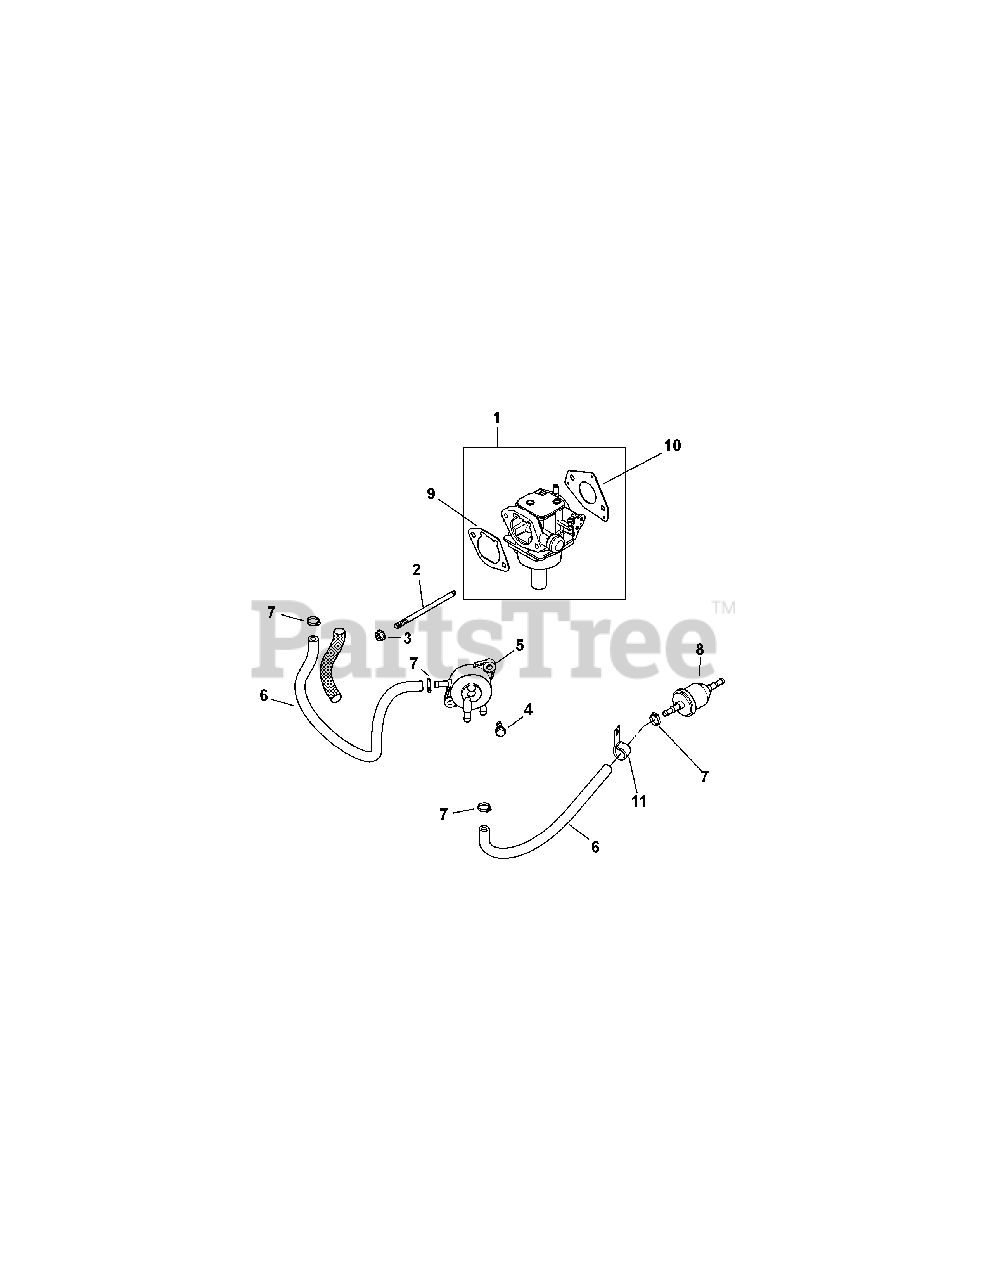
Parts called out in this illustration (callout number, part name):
1	Carburetor Kit
2	Stud, M6 x 1.0 x 106
3	Flange Nut, M6 x 1.0
4	Tap Screw, M6 x 1.7 x 18
6	Fuel Line
7	Hose Clamp, 1/2
9	Air Cleaner Base Gasket
10	Carburetor Gasket
